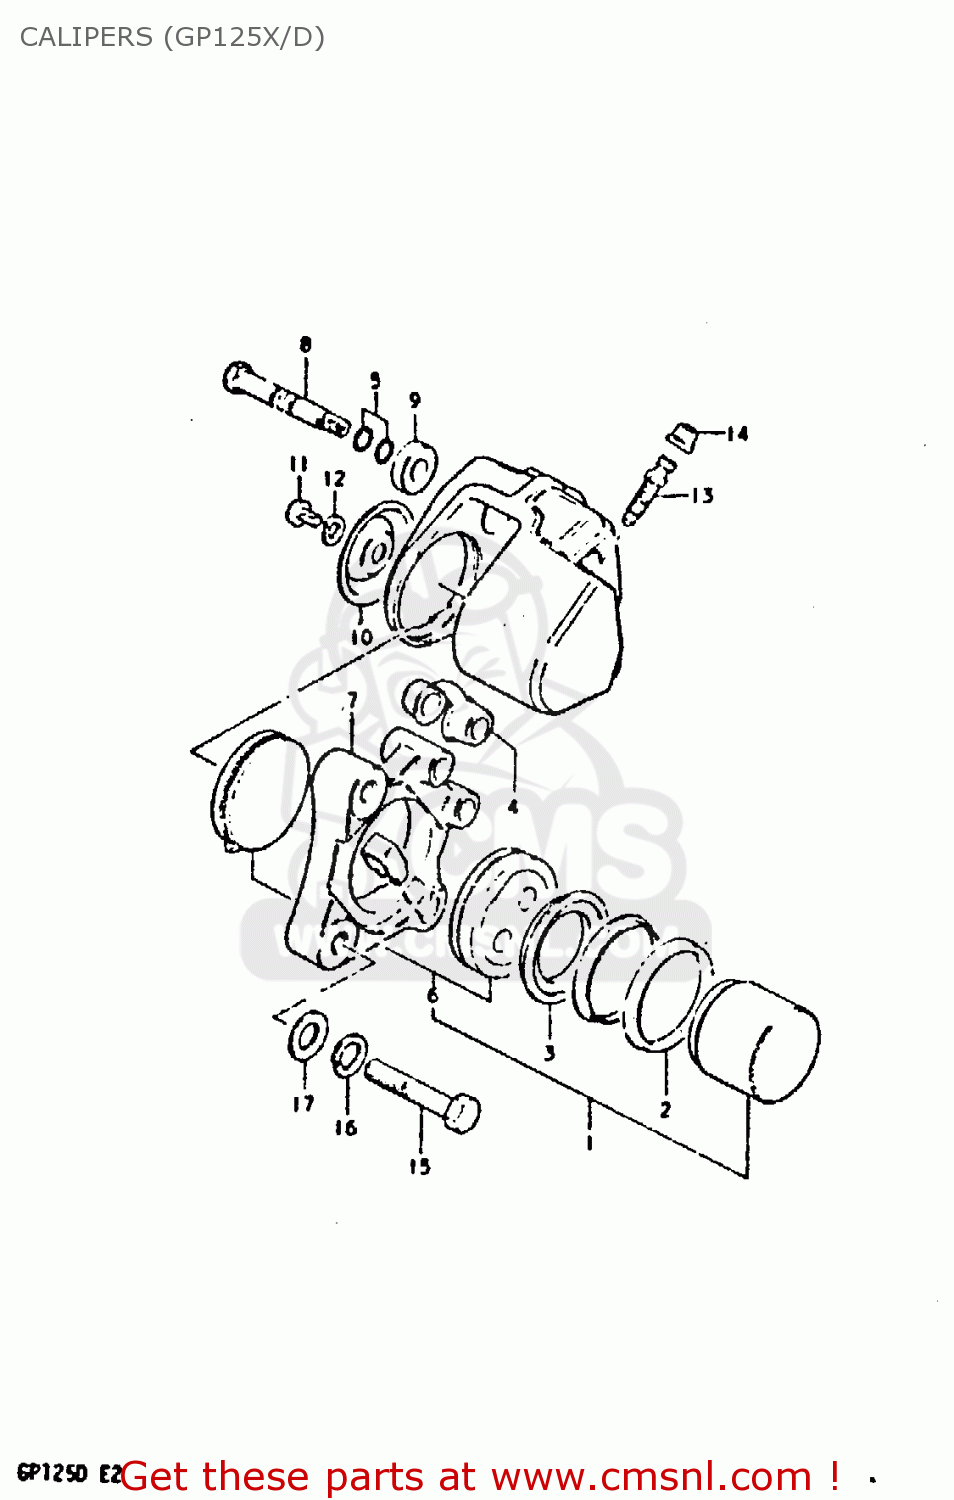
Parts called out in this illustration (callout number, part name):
1	PISTON & PAD SET
2	SEAL,PISTON
3	ROOT, PISTON
4	COVER,AXLE DUST
5	O RING, AXLE
6	PAD SET (MCA)
7	HOLDER, CALIPERS
8	AXLE,CALIPER
9	WASHER, AXLE
10	COVER,HOUSING
11	SCREW
12	LOCK WASHER
13	BLEEDER
14	CAP,BREATHER
15	BOLT
16	WASHER,LOCK,8.
17	WASHER
